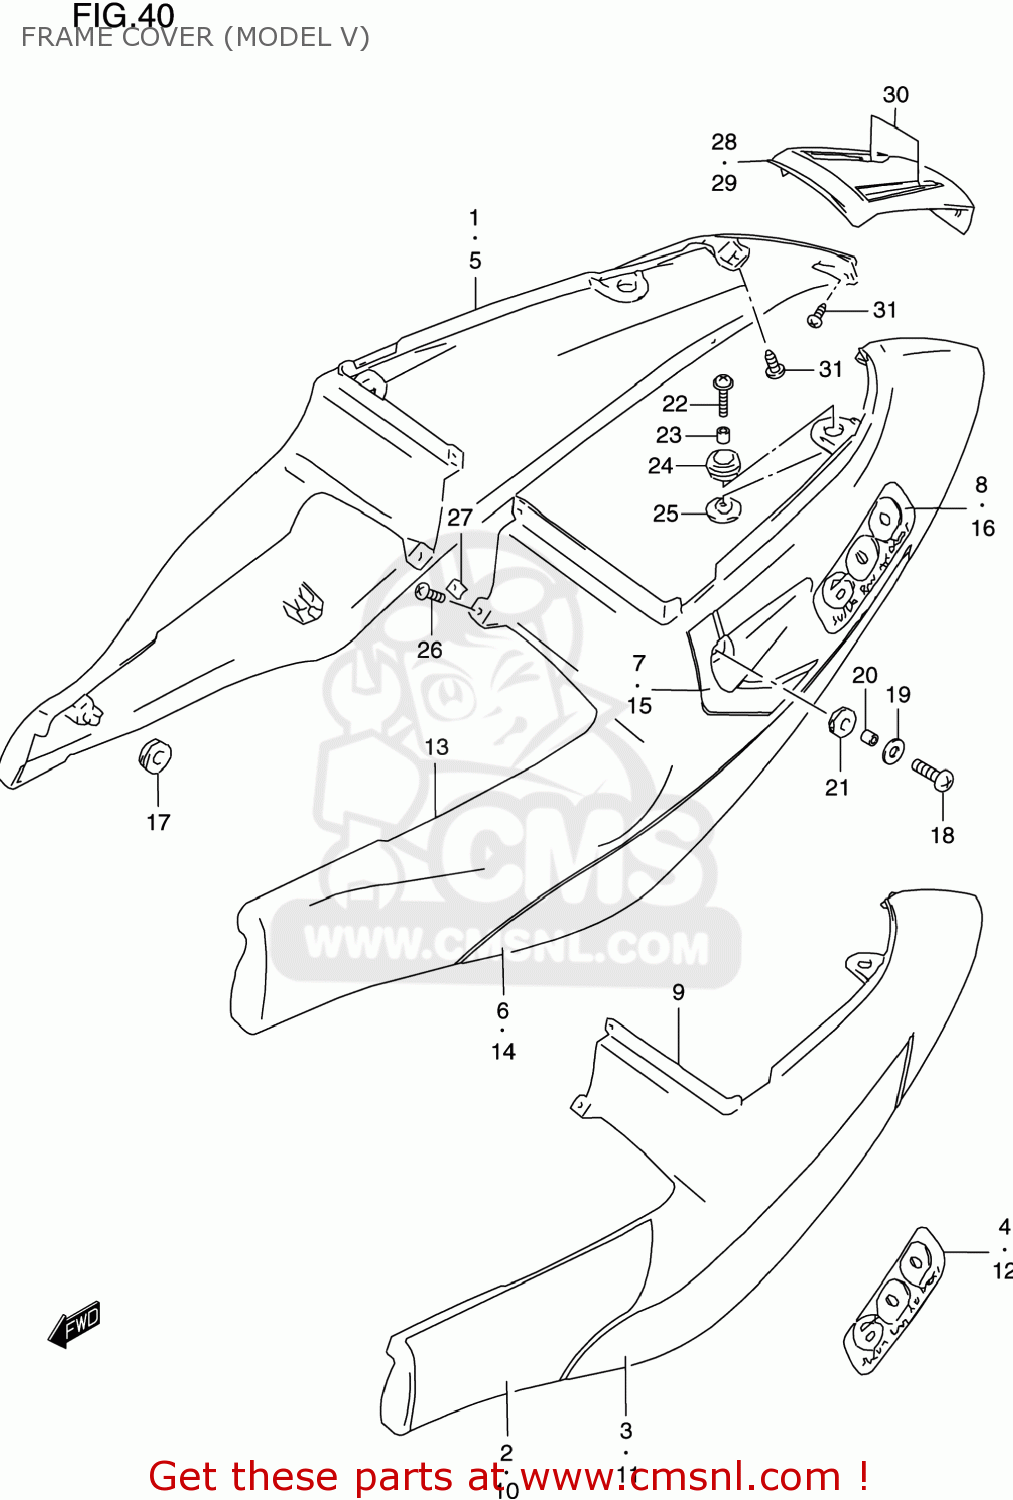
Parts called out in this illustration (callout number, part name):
1	COVER,FRAME,R(GRAY)
2	TAPE,FRAME COVER FR,R
3	TAPE,FRAME COVER RR,R
4	EMBLEM,FRAME COVER
5	COVER,FRAME,R(WHITE)
6	TAPE,FRAME COVER,R
7	TAPE,FRAME COVER STRIPE,R
8	EMBLEM,FRAME COVER
9	COVER,FRAME,L(GRAY)
10	TAPE,FRAME COVER FR,L
11	TAPE,FRAME COVER RR,L
12	EMBLEM,FRAME COVER
13	COVER,FRAME,L(WHITE)
14	TAPE,FRAME COVER,L
15	TAPE,FRAME COVER STRIPE,L
16	EMBLEM,FRAME COVER
17	CUSHION
18	SCREW(6X20)
19	WASHER(6.5X22X1.6)
20	SPACER(6.5X9X6.7)
21	CUSHION
22	SCREW(6X25)
23	SPACER(6.5X10X9.4)
24	CUSHION,TAIL COVER UPR
25	CUSHION,FRAME COVER LWR
26	SCREW
27	NUT
28	COVER,FRAME,CENTER
29	COVER COMP,FRAME,CENTER
30	TAPE SET,FRAME COVER CTR
31	SCREW
